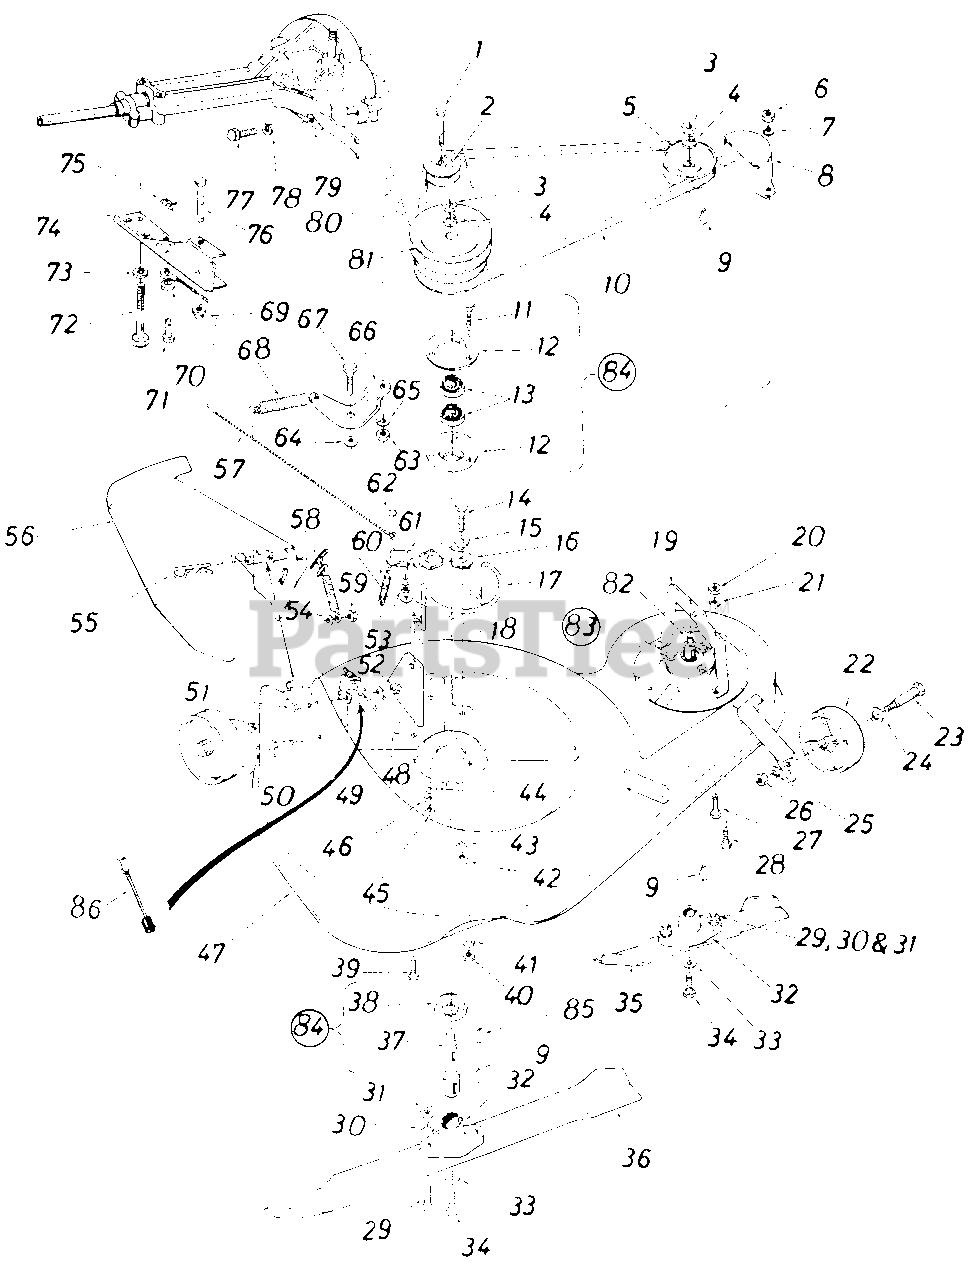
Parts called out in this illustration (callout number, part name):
1	Hex Bolt 3/8-24 x 1.50" Lg.
2	"V"-Idler Pulley 3.06" O.D.
3	Hex Jam Nut 5/8-18 Thd.
4	Bell-Wash. .630" I.D. x 1.25 x .090
5	Pulley 3.56" O.D. x 5/8
6	Hex Nut 1/4-20 Thd.
7	L-Wash. 1/4" I.D.*
8	Belt Guard Cover
9	#6 Hi-Pro Key 5/32 x 5/8" Dia.
10	V-Belt 1/2 x 53" Lg. (4L)
11	Hex Bolt 5/16-18 x .75" Lg.
12	Brg. Housing 1.85" I.D.
13	Ball Bearing .787" I.D. x 1.85" O.D.
14	Hex Bolt 5/16-18 x 1.0" Lg. (Grade 5)
15	Shld. Spacer .500" Dia. x .27" Lg.
16	Blade Brake Brkt. Ass'y.
17	Belt Guard
18	Fl-Wash. .344" I.D. x .875" O.D.
19	Deck Bracket
20	Hex Nut 5/16-18 Thd.
21	L-Wash. 5/16 I.D.
22	Deck Wheel 5.0" x 1.38"
23	Shoulder Bolt .498" Dia. x 1 .635
24	Belleville .400" I.D. x .88" O.D.
25	L-Wash. 3/8" I.D.
26	Hex Nut 3/8-16 Thd.
27	Hex Bolt 5/16-18 x .75" Lg.
28	Hex Bolt 1/4-20 x .62" Lg.
29	Hex Bolt 5/16-24 x 1.00" Lg. (Grade 5)
30	L-Wash. 5/16" I.D.
31	Hex Nut 5/16-24 Thd.
32	Blade Adapter
33	L-Wash. 3/8" I.D. H.D.
34	Hex Bolt 3/8-24 x 1.50" Lg. (Grade 5)
35	13" Blade
36	24" Blade
37	Blade Spindle (4.90" Lg.)
38	Bearing Shield
39	Hex Bolt 5/16-18 x .75" Lg.
40	Hex Nut 5/16-18 Thd.
41	L-Wash. 5/16" I.D.
42	Hex Nut 5/16-18 Thd.
43	L-Wash. 5/16" I.D.
44	Hex Nut 5/16-18 Thd.
45	Hex Nut 5/16-18 Thd.
46	L-Wash. 5/16" I.D.*
47	36" Deck Ass'y.
48	Ground Wire
49	Safety Switch
50	Truss Mach. Scr. 1/4-20 x .50" Lg.*
51	Hex Bolt 1/4-20 x .62" Lg.*
52	Hex Nut 1/4-20 Thd.*
53	L-Wash. 5/16" I.D.*
54	Fl-Wash. .281" I.D. x .50" O.D.
55	Internal Cotter Pin
56	Chute Deflector
57	Brake Cable Ass'y. (1 3.75" Lg.)
58	Spring Latch Ass'y.
59	Hex Nut 1/4-20 Thd.*
60	Extension Spring .38" O.D. x 3.25" Lg.
61	Hex Nut 5/16-18 Thd.*
62	Cap Speed Nut 1/4" Rod
63	Hex Nut 3/8-16 Thd.*
64	Fl-Wash. .344" I.D. x .875" O.D.
65	L-Wash. 3/8" I.D.*
66	Deck Idler Brkt. Ass'y.
67	Shoulder Bolt .498" Dia. x .710
68	Extension Spring
69	Cap Speed Nut 1/4" Rod
70	Fl-Wash. .281" I.D. x .50" O.D.
71	Clevis Pin 1/4" Dia. x .53" Lg.
72	Hex Bolt 5/16-18 x 2.75" Lg.*
73	L-Wash. 5/16" I.D.*
74	Lower Outside Belt Guard
75	Intern. Cot-Pin 5/16" Dia.
76	Weld Pin .25" Dia. x 2.5" Lg.
77	Hex Bolt 1/4-20 x .62" Lg.*
78	L-Wash. 1/4" I.D.*
79	Lower Inside Belt Guard
80	V-Belt 1/2 x 50" Lg.
81	Pulley 5.81" O.D. x 5/8
82	Blade Spindle (3.70" Lg.)
83	Spindle Ass'y.
84	Spindle Ass'y.
85	#61 Hi-Pro Key 3/16" x 5/8" Dia.
86	Wire Lead
